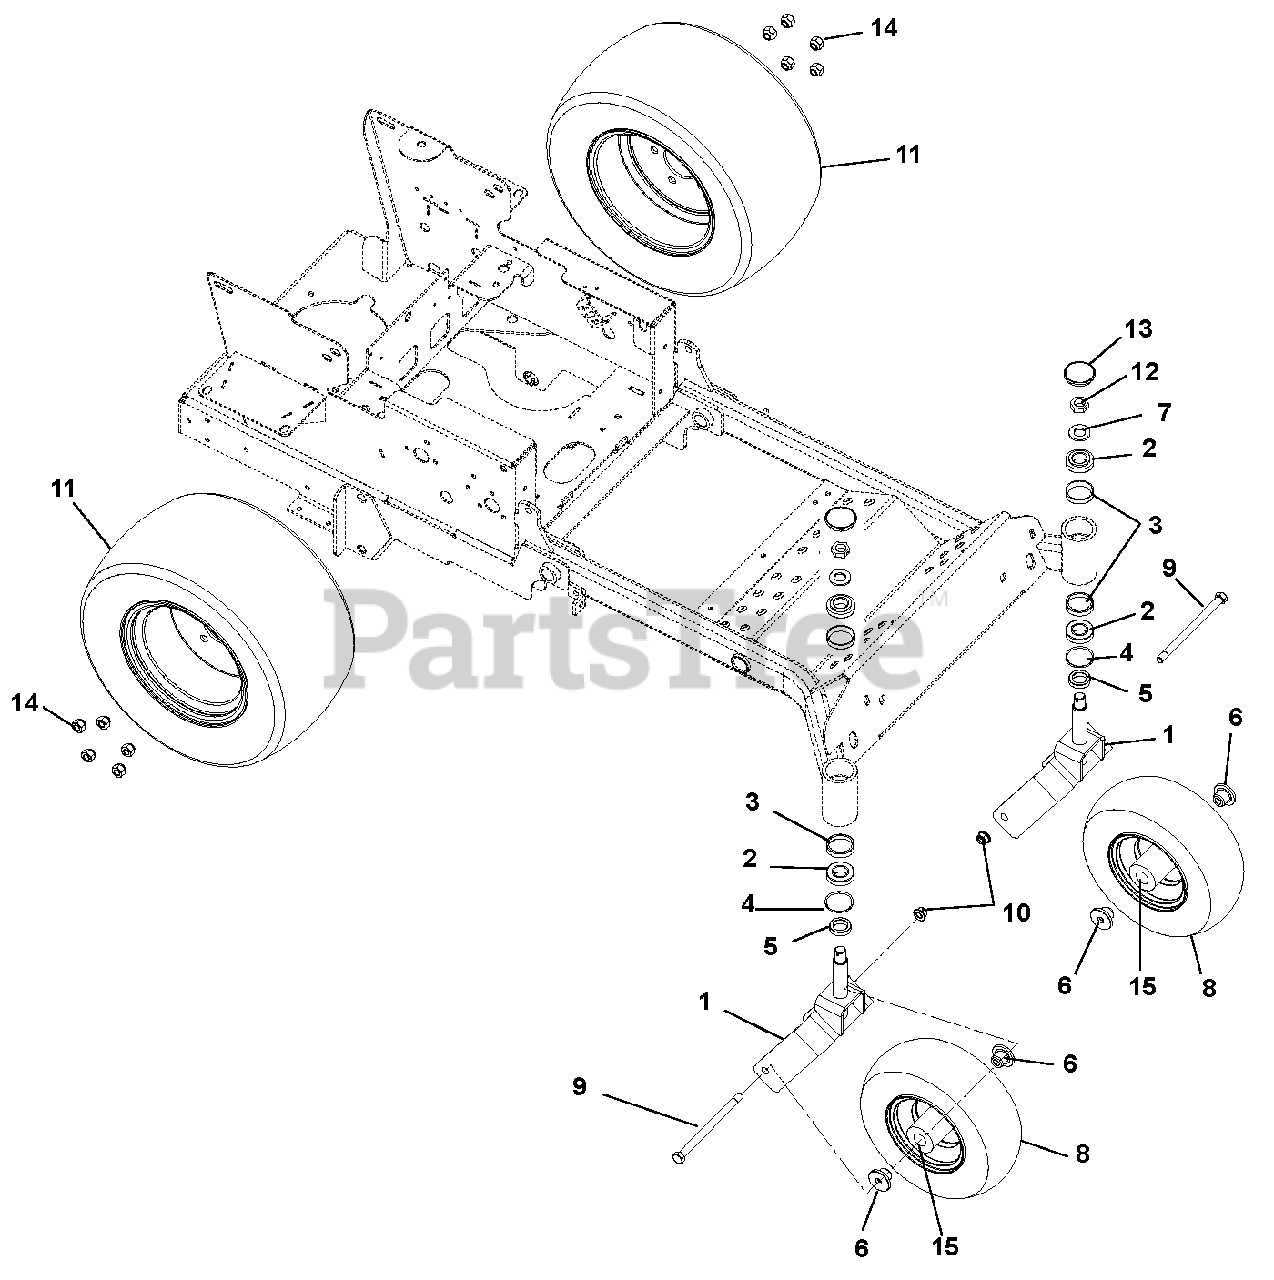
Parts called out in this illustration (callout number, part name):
1	Weldment, Front Fork
2	Bearing, Cone with Grease, 1.0 x .58
3	Bearing, Cup 1.980 x .420
4	Bearing Seal 1.5 x 2 x .18
5	Spacer, 1.005 I.D. x 1.507 O.D. x .375
6	Spacer, Wheel
7	Washer, Flat Steel .812 x 1.50 x .135
8	Tire/Wheel Assembly 13 x 5.00-6
8	Tire 13 x 5.00-6
9	Bolt, Hex .50-13 x 7.50 Grade 5
10	Nut, Nyloc Flange .50-13
11	Tire/Wheel Assembly, 20 x 10.00-10
11	Tire, 20 x 10.00-10
12	Nut, Center Lock Jam .75-16
13	Cap, Dust
14	Wheel Nut .50-20
15	Bearing, 25mm ID x 52mm OD x 15mm
